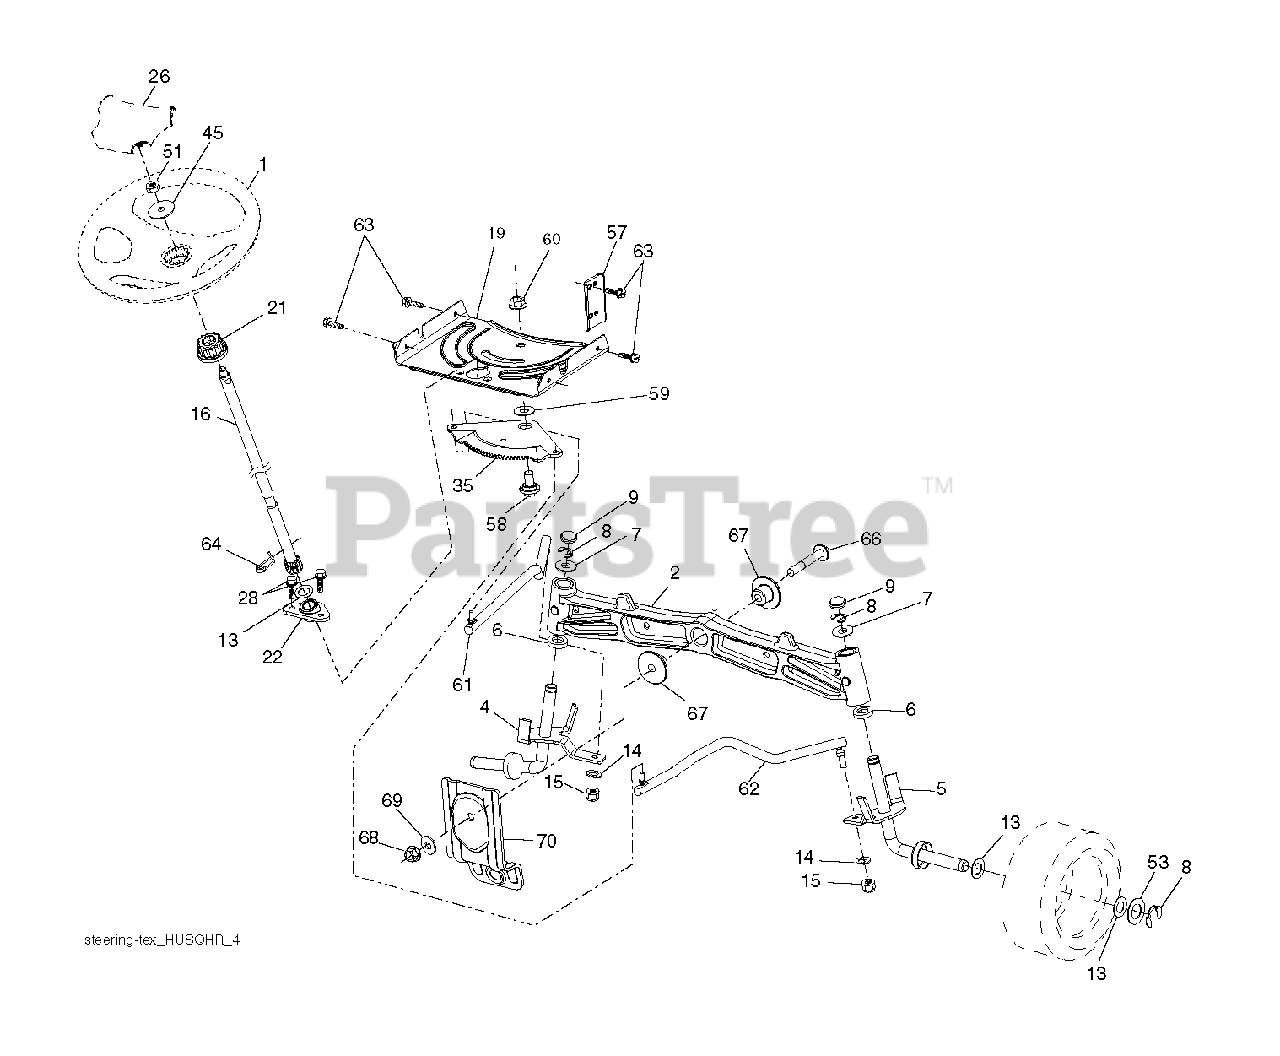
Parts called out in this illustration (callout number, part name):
1	WHEEL.STEER.HUSQ.SR.498.OVMLD
2	AXLE.CAST.IRON
4	SPINDLE.WELDED.LH.15"TEX
5	SPINDLE.WELDED.RH.15"T
6	THRUST WASHER
9	CAP.SPINDLE.BLACK
14	WASHER, LOCK 3/8
15	NUT CROWNLOCK 3/8-24
16	SHAFT, STEERING
19	PLATE.STEER.DDL.NLT/NG
21	ADAPTER, WHEEL STNG..
22	STEERING.SUPT.LOWER.
26	INSERT.CAP.WHL.STRG.HUSQ.PREM
28	SCREW, 3/8-16X3/4
35	GEAR.SECTOR.PLATE.DDL.
45	WASHER 9/16"ID, 2 3/8"OD
51	NUT.HEX.1/2-20
53	WASHER.HARDENED
57	BRKT.UPSTOP.GT/LT.TEX
58	BOLT.SHOULDER.SECTOR.P
59	WASHER.THURST.SECTOR.S
60	NUT FLANGE LOCK 5/8-11
61	DRAGLINK.LH.BALLSTUD.D
62	DRAGLINK.RH.BALLSTUD.D
63	SCREW
64	RETAINER.CLIP.SPRING.S
66	BOLT HEX FGHD 7/16-14 X 3 SERR
67	BUSHING.PM.FRONT AXLE
68	NUT.LOCK.FLANGE.7/16
69	WASHER.1.5X.505X.118
70	BRKT.DECK.SUSPENSION.F
